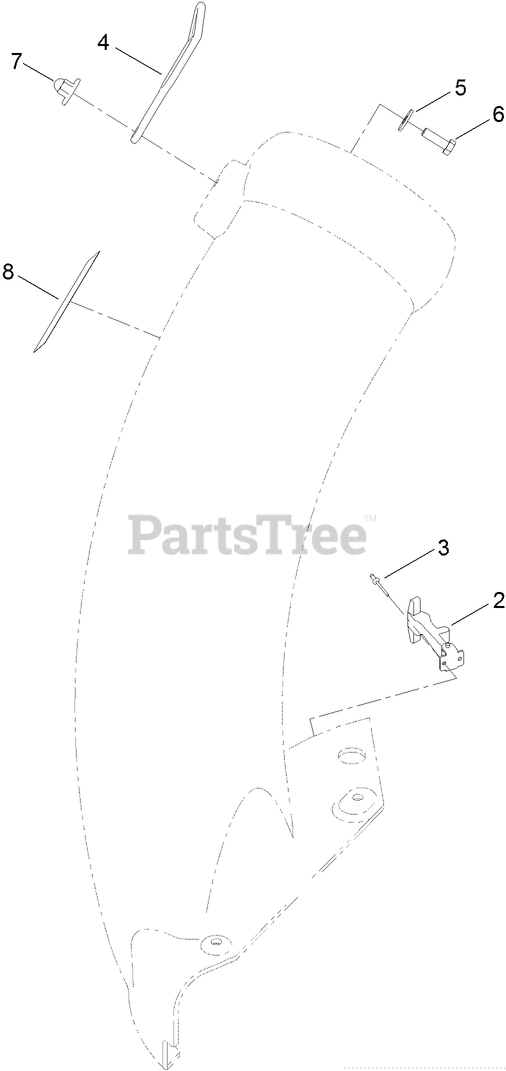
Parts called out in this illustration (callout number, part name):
2	HANDLE ASM
3	RIVET-POP
4	RETAINER-DUCT
5	WASHER-FLAT
6	SCREW-HH
7	NUT-IMPELLER
8	DECAL-DANGER
